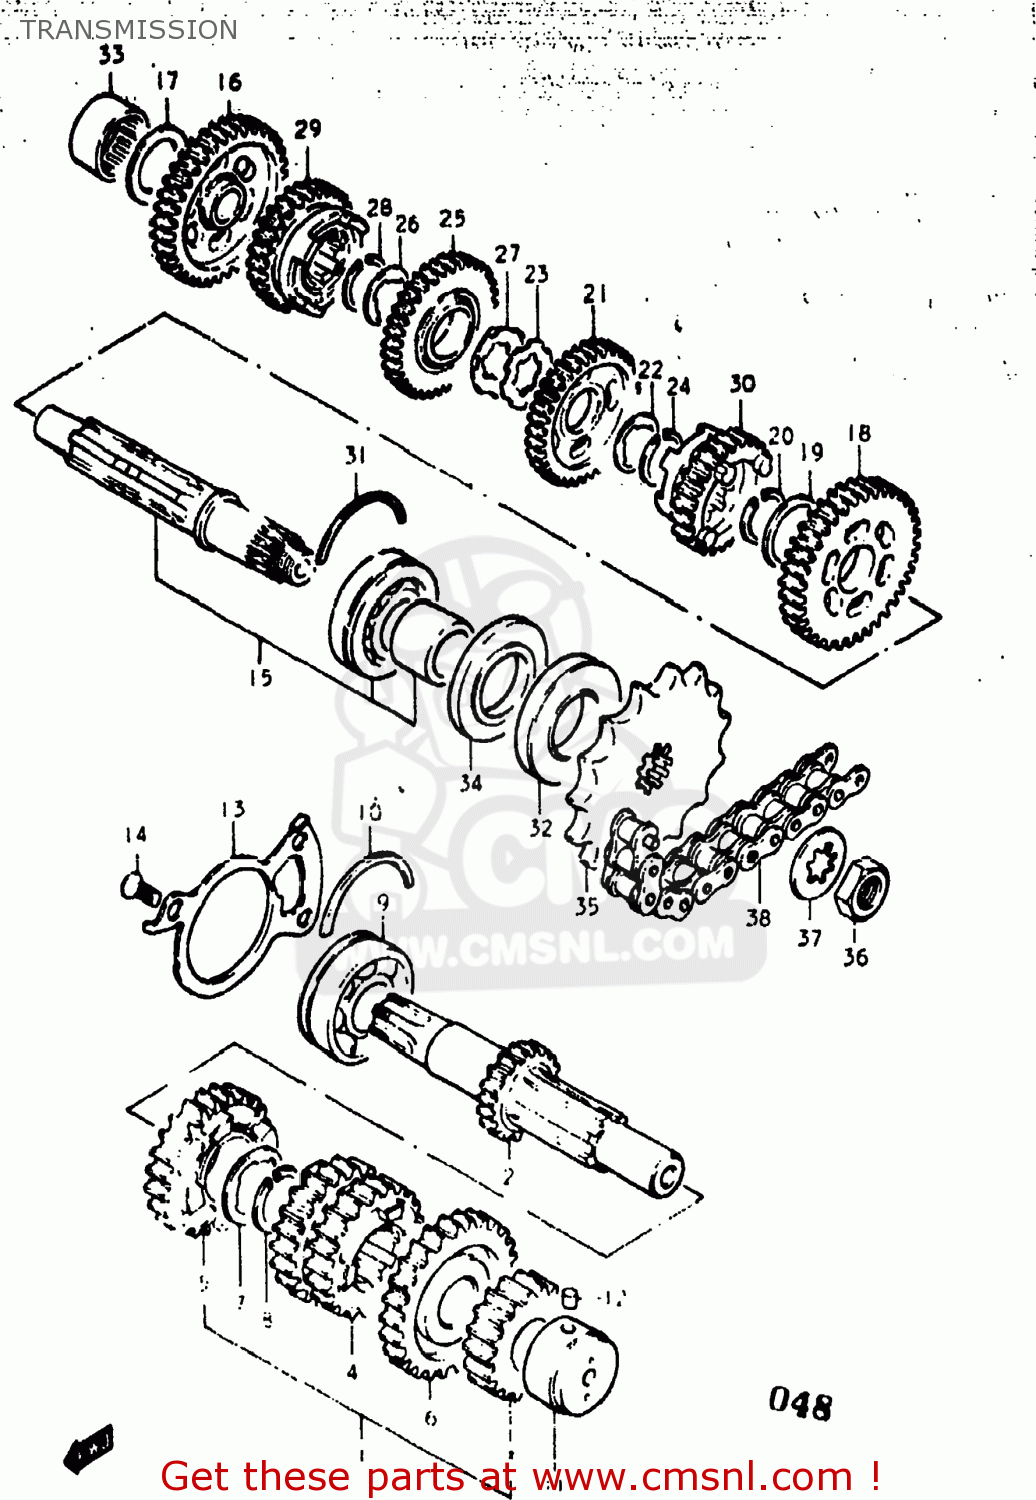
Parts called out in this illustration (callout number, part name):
1	SHAFT,COUNTER
2	SHAFT,COUNTER
3	GEAR,2ND DRIVE(NT:18)
4	GEAR,THIRD DRIVE
5	GEAR,FIFTH DRIVE
6	GEAR,SIXTH DRIVE
7	WASHER,LOCK
8	CIRCLIP
9	BEARING(25X62X17)
10	C-RING
11	ROLLER BEARING (20X34X2
12	PIN
13	PLATE,COUNTERSHAFT BEARING
14	SCREW
15	SHAFT,DRIVE
16	GEAR,FIRST DRIVEN
17	WASHER
18	GEAR,SECOND DRIVEN
19	WASHER
20	CIRCLIP
21	GEAR,THIRD DRIVEN
22	WASHER,LOCK
23	WASHER,LOCK
24	CIRCLIP
25	GEAR,FOURTH DRIVEN
26	WASHER,LOCK
27	WASHER
28	CIRCLIP
29	GEAR,FIFTH DRIVEN
30	GEAR,SIXTH DRIVEN
31	C-RING
32	OIL SEAL
33	ROLLER BEARING (20X34X1
34	SEAL,OIL(32X62X5.5)
35	SPROCKET,ENGINE(NT:16)
36	NUT
37	WASHER
38	CHAIN ASSEMBLY,DRIVE
